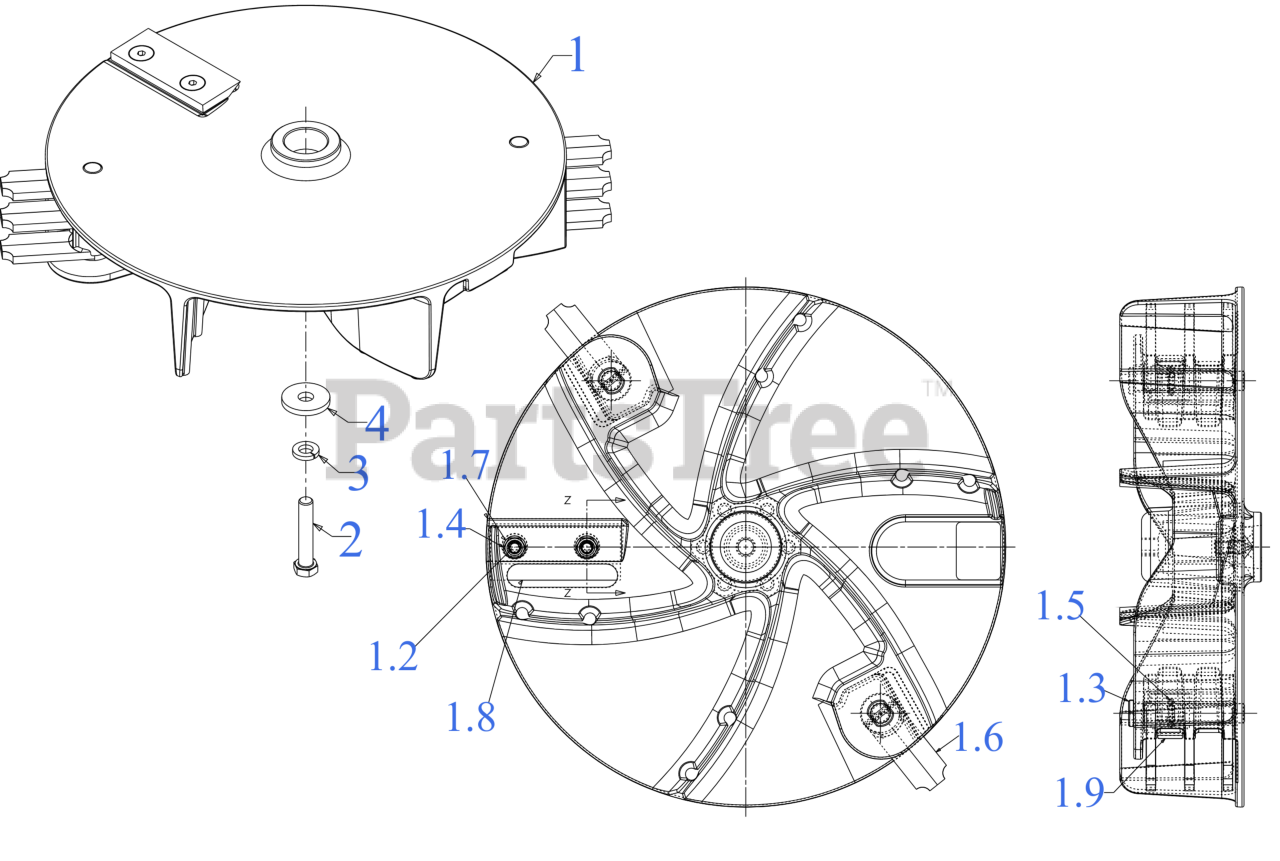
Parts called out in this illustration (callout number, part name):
1	IMPELLER ASSEMBLY
1.2	SCREW-SOC HD CSK 5/16-24-1.0 CS
1.3	CLEVIS PIN DIA .49
1.5	PIN SPIROL .156X1
1.6	FLAIL BLADE
1.7	LOCK WASHER 5/16
1.8	CHIPPER BLADE
1.9	RETAINING PIN CLIP
2	SCREW 3/8-24 X2.00 GR8
3	LOCK WASHER 3/8HD
4	FLAT WASHER
